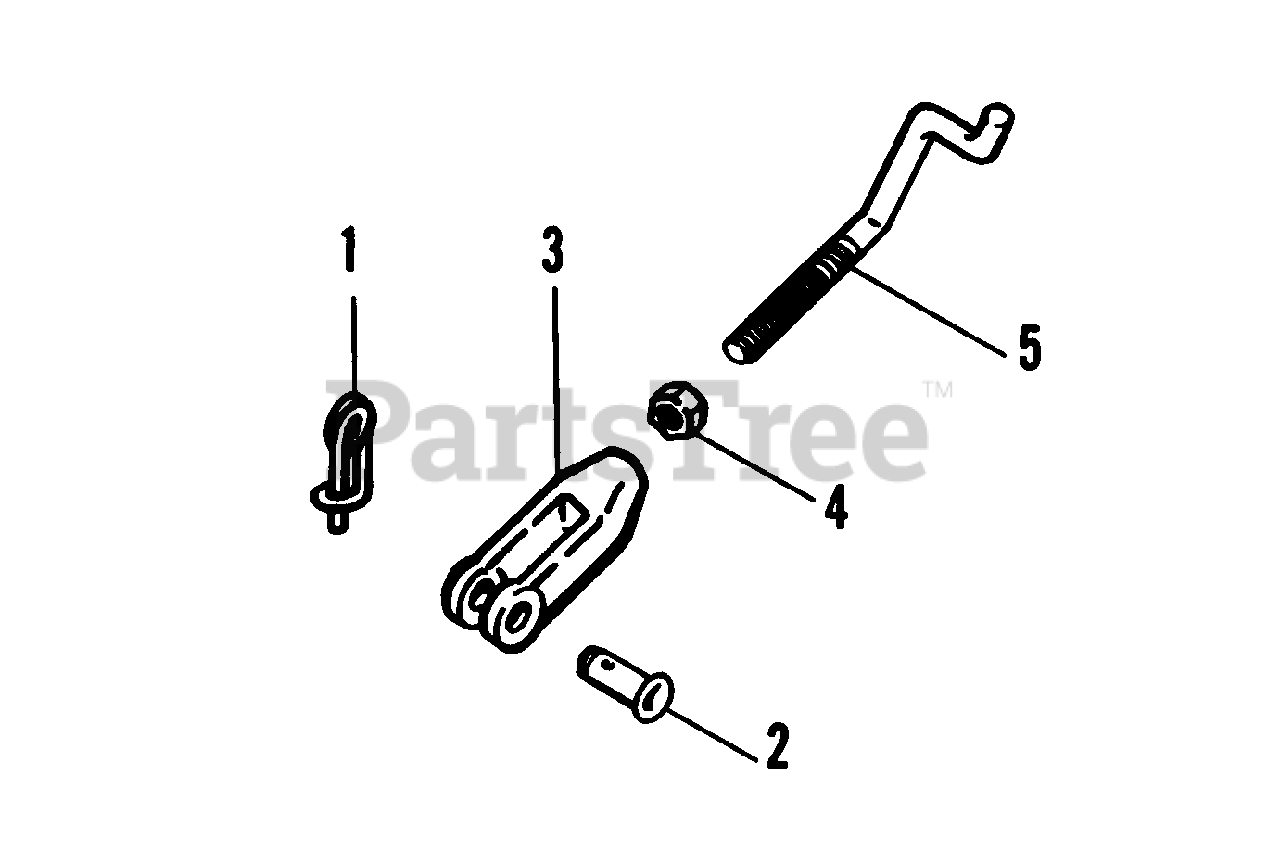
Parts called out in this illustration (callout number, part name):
1	CLIP
2	PIN
4	NUT, Jam, 5/16-18
5	ROD, Lift (Incl. Ref. Nos. 1 thru 4)
